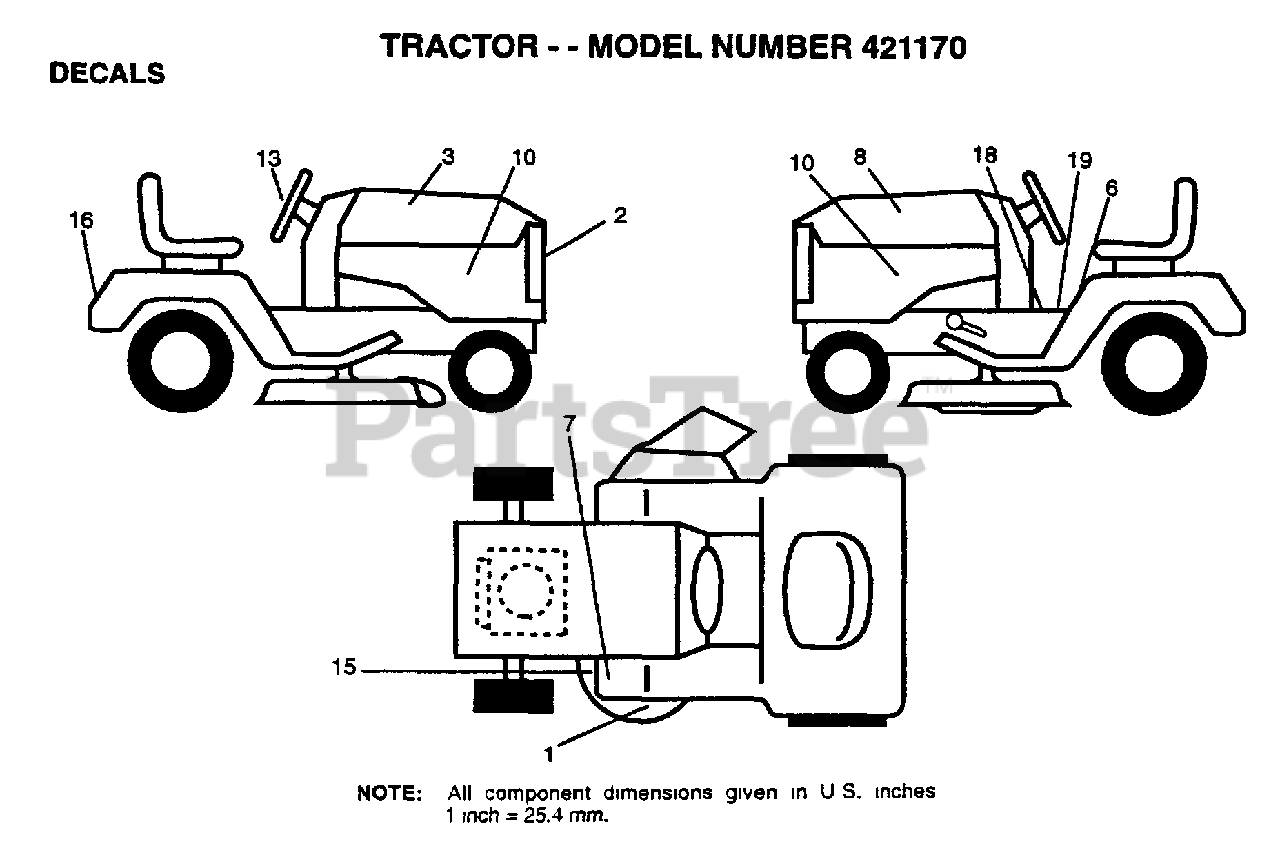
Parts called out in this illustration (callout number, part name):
2	DECAL.LENS.YP.EUR
3	DECAL.HD.RH.
6	DECAL
8	DECAL.HD.LH.
10	DECAL.PANEL.SD.
13	DECAL.INS.STRG.WH
15	DECAL
18	DECAL SADLE HYDRO
